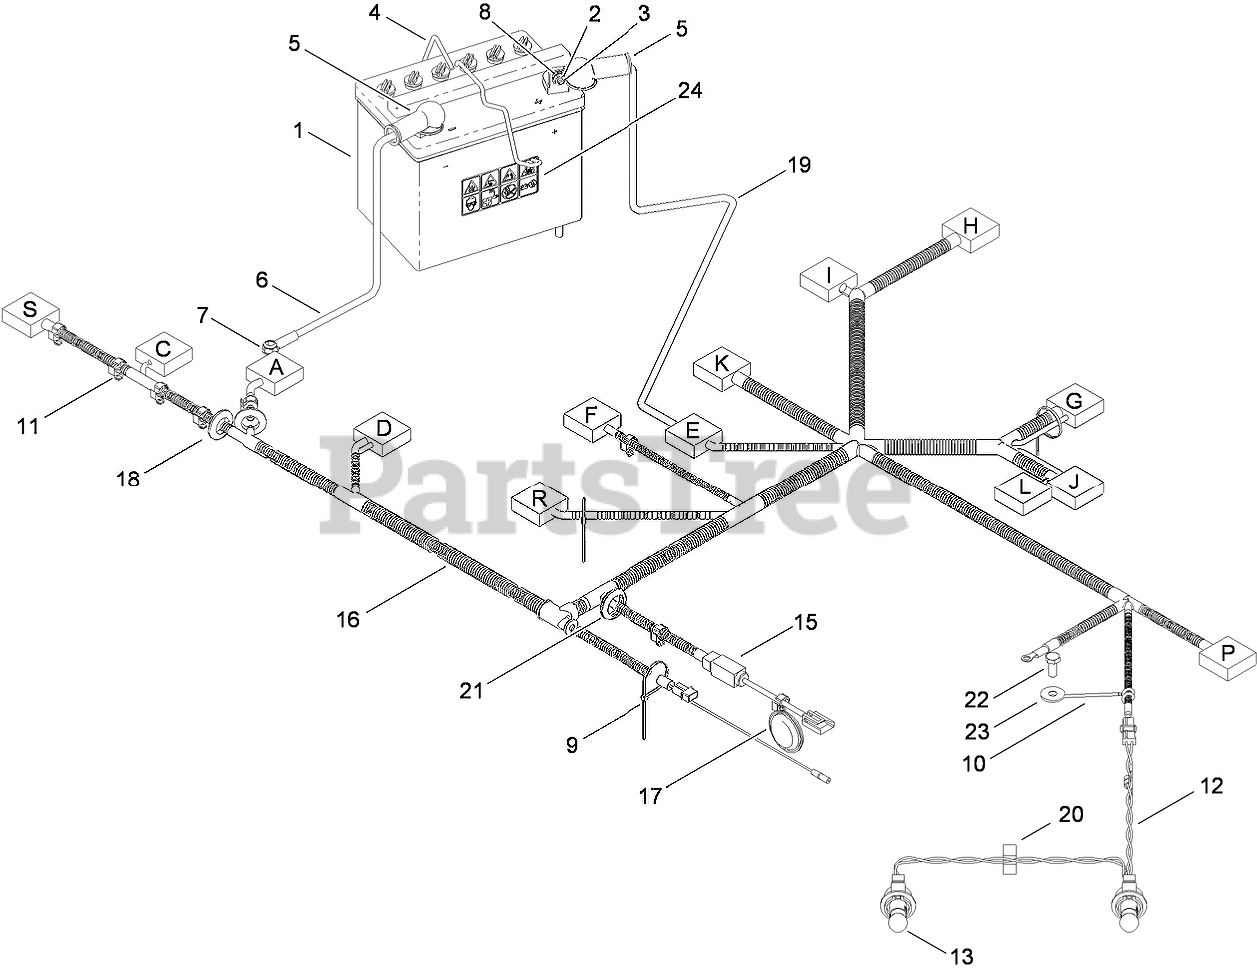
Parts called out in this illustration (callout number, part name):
1	BATTERY
2	NUT-HEX
3	SCREW-HH
4	CLAMP-BATTERY
5	BOOT-RUBBER
6	CABLE-BATTERY, NEGATIVE
7	NUT-LOCK, NI
8	WASHER-FLAT
9	TIE-CABLE
10	HOLDER-HARNESS, WIRING
11	CLIP-SNAP
12	HARNESS-WIRE, LIGHT
13	BULB-LIGHT
15	HARNESS-CLUTCH
16	HARNESS-WIRING
18	BUSHING
19	CABLE-BATTERY, POSITIVE
20	CLIP-NYLON
21	BUSHING
22	SCREW-HH
23	WASHER-PLAIN
24	DECAL-DANGER
